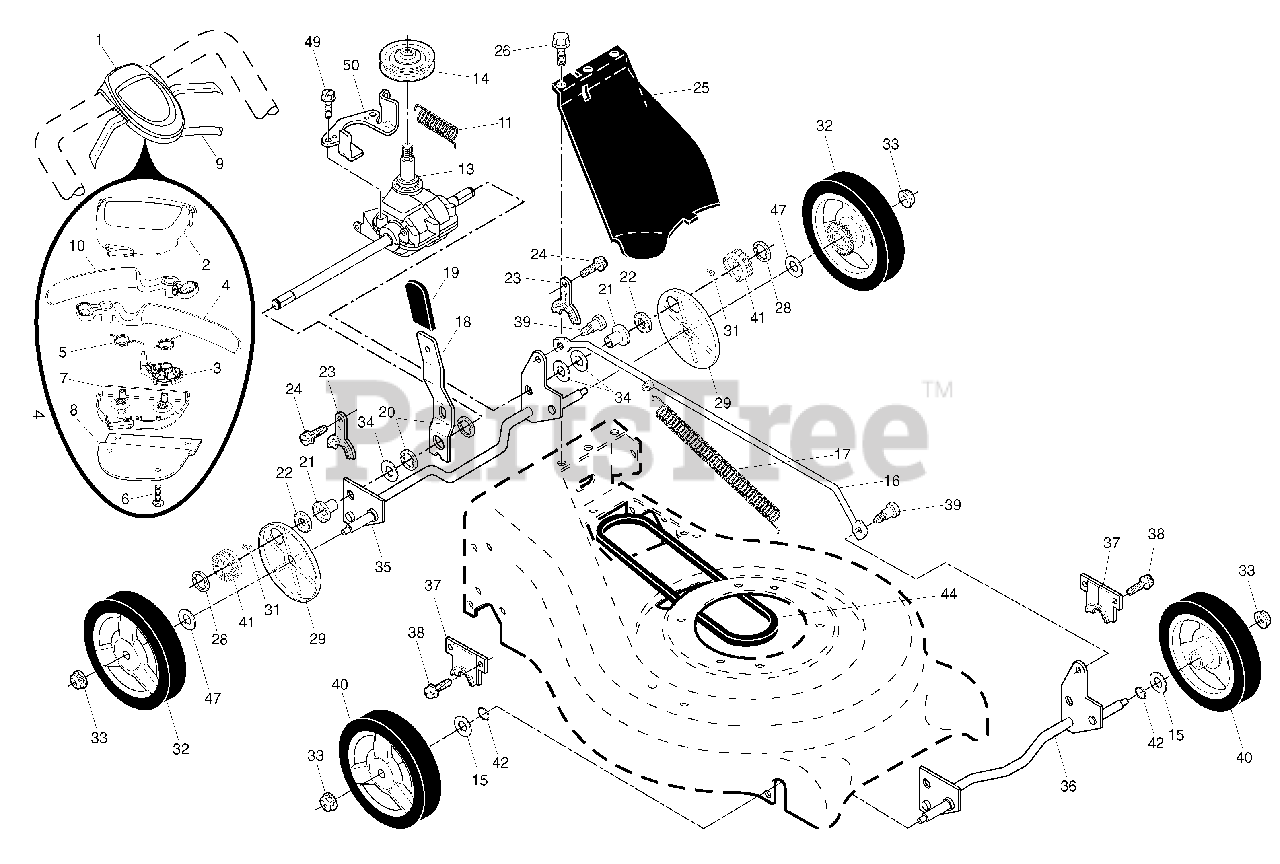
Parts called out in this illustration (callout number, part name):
1	Drive Control Assembly
2	Cover, Top, Drive Control
4	Lever, Drive Control, LH
5	Spring, Drive Control
6	Screw, Phillips Head #10 x 5/8
7	Cover, Bottom, Drive Control
8	Mounting Bracket, Drive Control
9	Cable, Drive Control
10	Lever, Drive Control, RH
13	Gear Case Assembly, Complete
14	Pulley, Drive
16	Rod, Connecting
17	Spring, Extension
18	Spring Selector
19	Knob, Selector Spring
21	Bearing, Support
22	Bearing, Ball
23	Retainer, Drive Assembly, Stamped
24	Screw, Tapping, Hex Head 1/4-20 x 5/8
25	Cover Drive
26	Screw, Threaded, Rolled #10-25 x .50
28	E-Ring 7/16
29	Cover, Dust, Wheel
32	Wheel, Driven, Rear 8 x 1-3/4
33	Nut, Hex, Flangelock 3/8-16
34	Washer, Flat
35	Shaft Assembly, Rear
36	Shaft Assembly, Front
37	Retainer, Front Shaft
38	Screw #12 x 5/8
39	Bolt, Shoulder, Semi-Gimlett Point
40	Wheel, Front 8 x 1-3/4
47	Washer 1/2 x 1-1/2 x .134
49	Screw #12 x 5/8
50	Bracket, Belt
